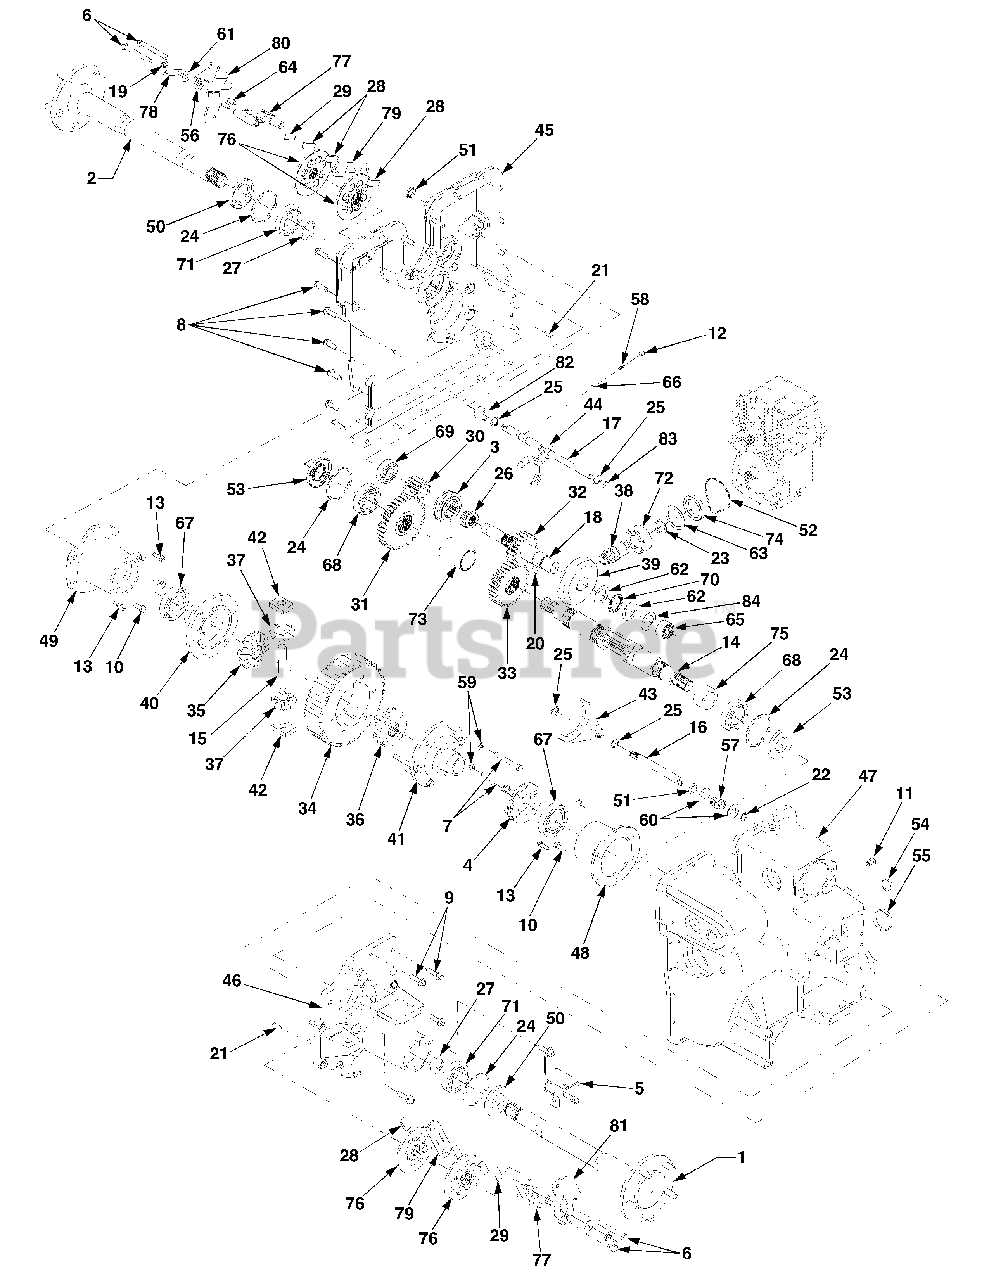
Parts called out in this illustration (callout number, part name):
1	Shaft, Axle RH
2	Shaft, Axle LH
3	Collar, Shift
4	Collar Assembly, Diff Lock
5	Bracket, Diff. Lock
6	Screw, Hex Cap, 5/16-18 x 2.75 GR5
7	Screw, Hex Cap, 5/16-18 x 2.5 GR5
8	Screw, Hex Wash. Hd. Tapp, 5/16-18 x 1.0
9	Screw, Hex Wash. Hd. Tapp, 5/16-18 x 1.25
10	Screw, Hex Cap, w/Patch 5/16-18 x .75GR5
11	Screw, Plug, M14 x 1.5 x .827
12	Screw, Set, 5/16-18 x .375
13	Screw, Shoulder .309 x .375: 1/4-20
14	Shaft, Output, 11T
15	Shaft, Cross, .625 x 3.95
16	Shaft, Diff. Lock Actuator
17	Shaft, Hi-Lo Actuator
18	Shaft, Drive
19	Nut, Hex Insert Lock, 5/16-24
20	Key, Woodruff, 1/4 x 3/4
21	Pin, Dowel, .25 x .75
22	Ring, Retaining
23	Ring, Snap
24	Ring, Retaining
25	Clip, Rotor
26	Gear, Hi-Lo Spline Coupling
27	Ring, Retaining
28	Pad, Brake
29	Plate, Brake Puck
30	Gear, Spur, 12T : Low
31	Gear, Spur, 34T
32	Gear, Spur, 19T
33	Gear, Spur, 27T
34	Gear, Spur, 56T
35	Gear, Bevel, 16T
36	Gear, Bevel, 16T Lock
37	Gear, Bevel, 10T Diff.
38	Gear, Spiral Bevel, 13T
39	Gear, Spiral Bevel, 54T
40	Cover, Differential
41	Cover, Differential Lock
42	Block, Thrust
43	Yoke, Diff. Lock Actuator
44	Yoke, Shift, Hi-Lo
45	Cover, Trans. Large
46	Cover, Trans. Small
47	Housing, Trans.
48	Housing, Axle Inner - RH
49	Housing, Axle Inner - LH
50	Seal, Oil
51	Seal, Oil
52	Seal, Gland
53	Seal, Oil
54	Plug, Oil
56	Spring, Torsion
57	Spring, Compression, .845 x 1.0
58	Spring, Compression, .24 x .563
59	Washer, Lock, 5/16
60	Washer, Flat, .597 x 1.0 x .04 ..
61	Washer, Flat, .343 x .88 x .062
62	Washer, Thrust
63	Washer, Flat, 1.52 x 2.0 x .030
63	Washer, Flat, 1.52 x 2.0 x .005
63	Washer, Flat, 1.52 x 2.0 x .015
64	Pin, Brake Actuating
65	Bearing, Needle
66	Ball, Detent
67	Bearing, Ball
68	Bearing, Ball
69	Bearing, Ball
70	Bearing, Needle Thrust
71	Bearing, Ball
72	Bearing, Ball
73	Spacer, 1.51 x 1.75 x 2.41
74	Spacer, 1.515 x 2.039 x .335
75	Spacer, 1.26 x 1.625 x .853
76	Disc, Brake
77	Yoke, Brake
78	Bracket, Brake Anti Rotation
79	Plate, Puck Retainer
80	Arm, Brake Actuator - LH
81	Arm, Brake Actuator - RH
82	Spacer, .573 x .938 x .832
83	Plug, .437 x .16
84	Washer, Flat, 1.0 x 1.56 x .010
84	Washer, Flat, 1.0 x 1.56 x .020
84	Washer, Flat, 1.0 x 1.56 x .015
